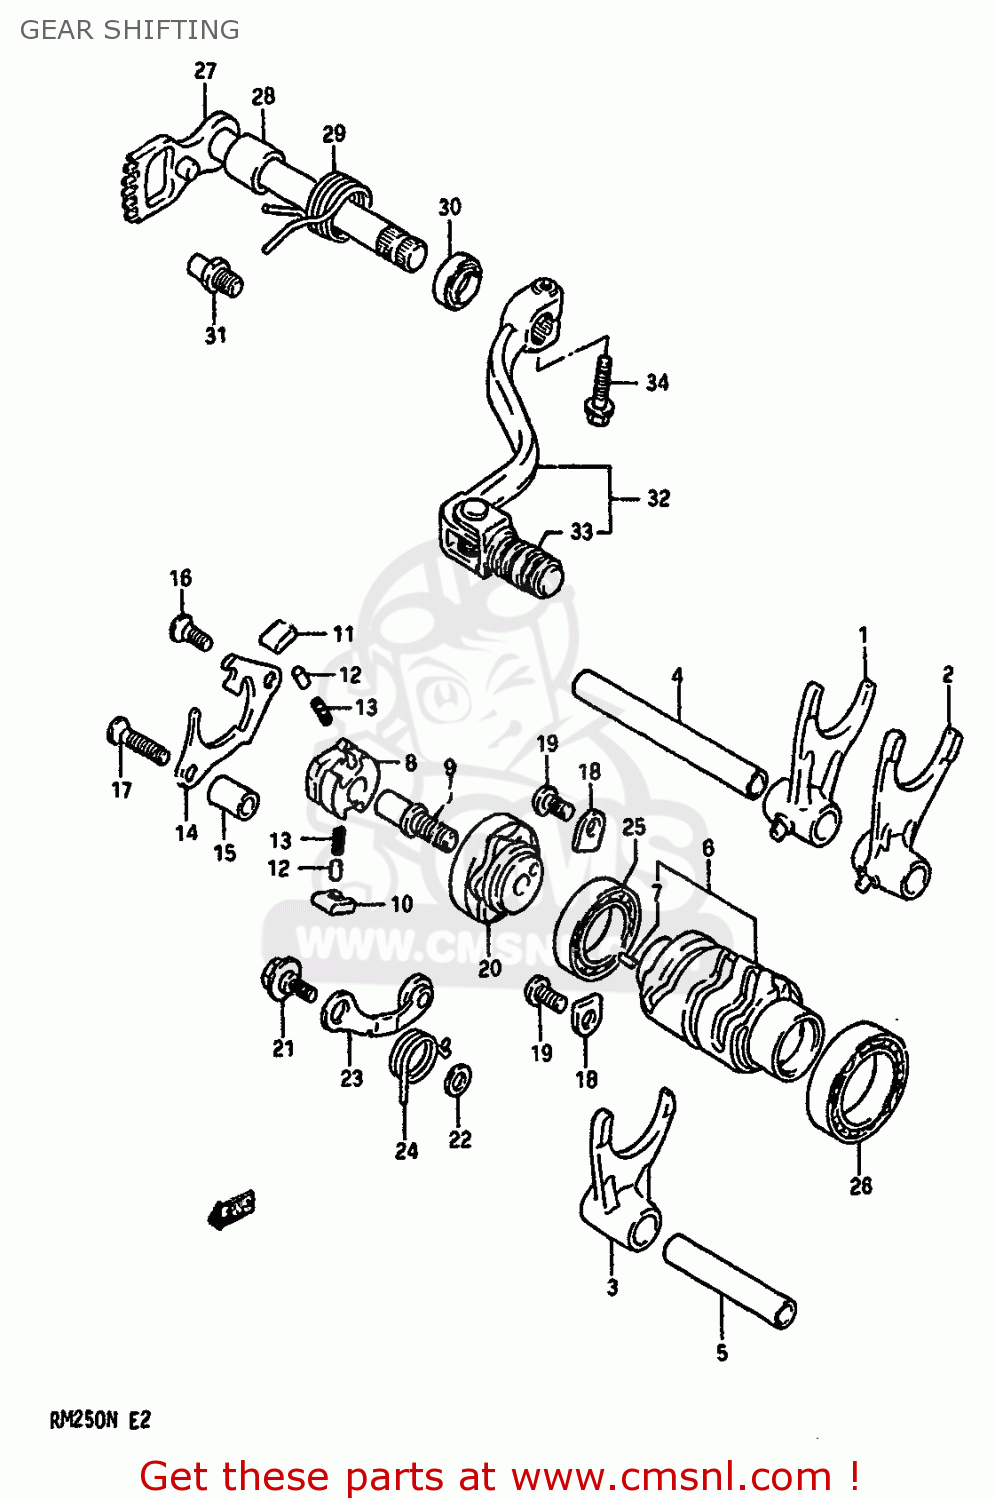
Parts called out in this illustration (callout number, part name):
1	FORK,GEAR SHIFT NO.1
2	FORK,GEAR SHIFT NO.2
3	FORK,GEAR SHIFT NO.3
4	SHAFT,GEAR SHIFT FORK
5	SHAFT,GEAR SHIFT FORK
6	CAM,GEAR SHIFT
7	PIN
8	GEAR,GEARSHIFT CAM DRIVE
9	PIN,SHIFT CAM DRIVEN GEAR
10	PAWL,GEAR SHIFT NO.1
11	PAWL,GEAR SHIFT NO.2
12	PIN(5X8)
13	SPRING
14	LIFTER,GEAR SHIFT POLE
15	SPACER(6.2X12X18)
16	SCREW
17	SCREW
18	RETAINER,SHIFT CAM,R BEARING
19	SCREW 6X12
20	PLATE,GEAR SHIFT CAM STOPPER
21	BOLT(6X14.3)
22	WASHER
23	STOPPER,SHIFT CAM
24	SPRING
25	BEARING
26	BEARING(30X37X12)
27	SHAFT,GEAR SHIFT
28	SPACER(14X20X17.5)
29	SPRING
30	SEAL,OIL(14X22X7.3)
31	STOPPER,GEAR SHIFT CAM
32	LEVER ASSEMBLY,GEAR SHIFTING
33	RUBBER,GEAR SHIFT PEDAL
34	BOLT
